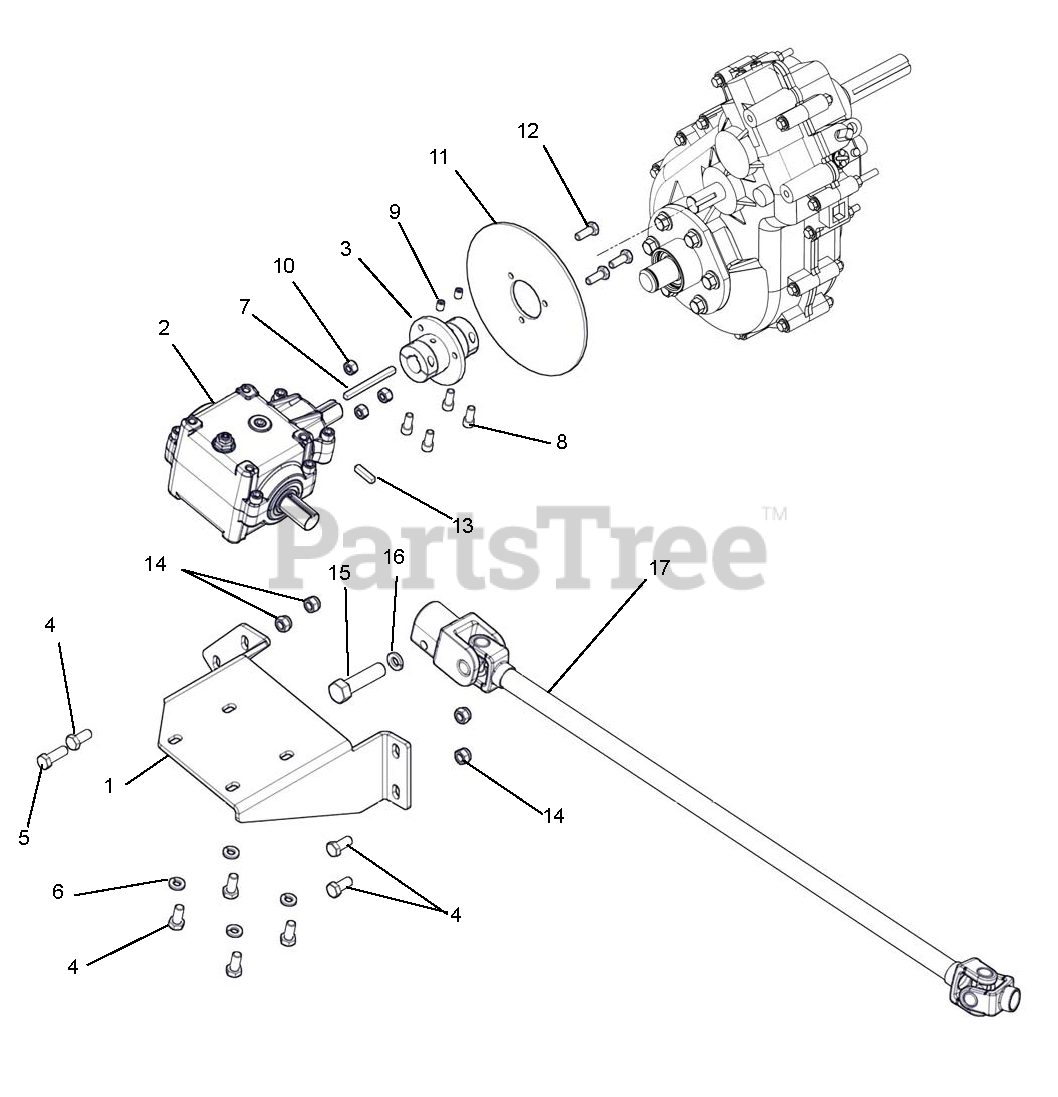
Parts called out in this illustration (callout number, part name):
1	4X4 MOUNT PLATE
2	GBOX MODEL R100 1.5TO1 RATIO
3	COUPLER, SHORT
4	@BLT-HEX .31-18X.75 GR5 YWZC
5	@BLT-HEX .31-18X1.00 GR5 YWZC
6	@WSHR-LK .31X.078 REG YWZC
7	KEY, .188 X .188 X 2.50 SQ
8	HSHCS 1/4-28X5/8
9	SCR-SET .25-28X.375 SK CUP
10	@NUT-LK-CTR .25-20 YWZC
11	DISK, PARK BRAKE
12	@BLT-HEX .25-20X.75 GR5 YWZC
13	KEY 3/16 X 7/8
14	@NUT-LK-NYL .312-18 YWZC
15	@BLT-HEX .38-16X2.00 GR5 YWZC
16	@WSHR-LK .38X.094 REG YWZC
17	REAR HALF DRIVELINE 4X4 ST
